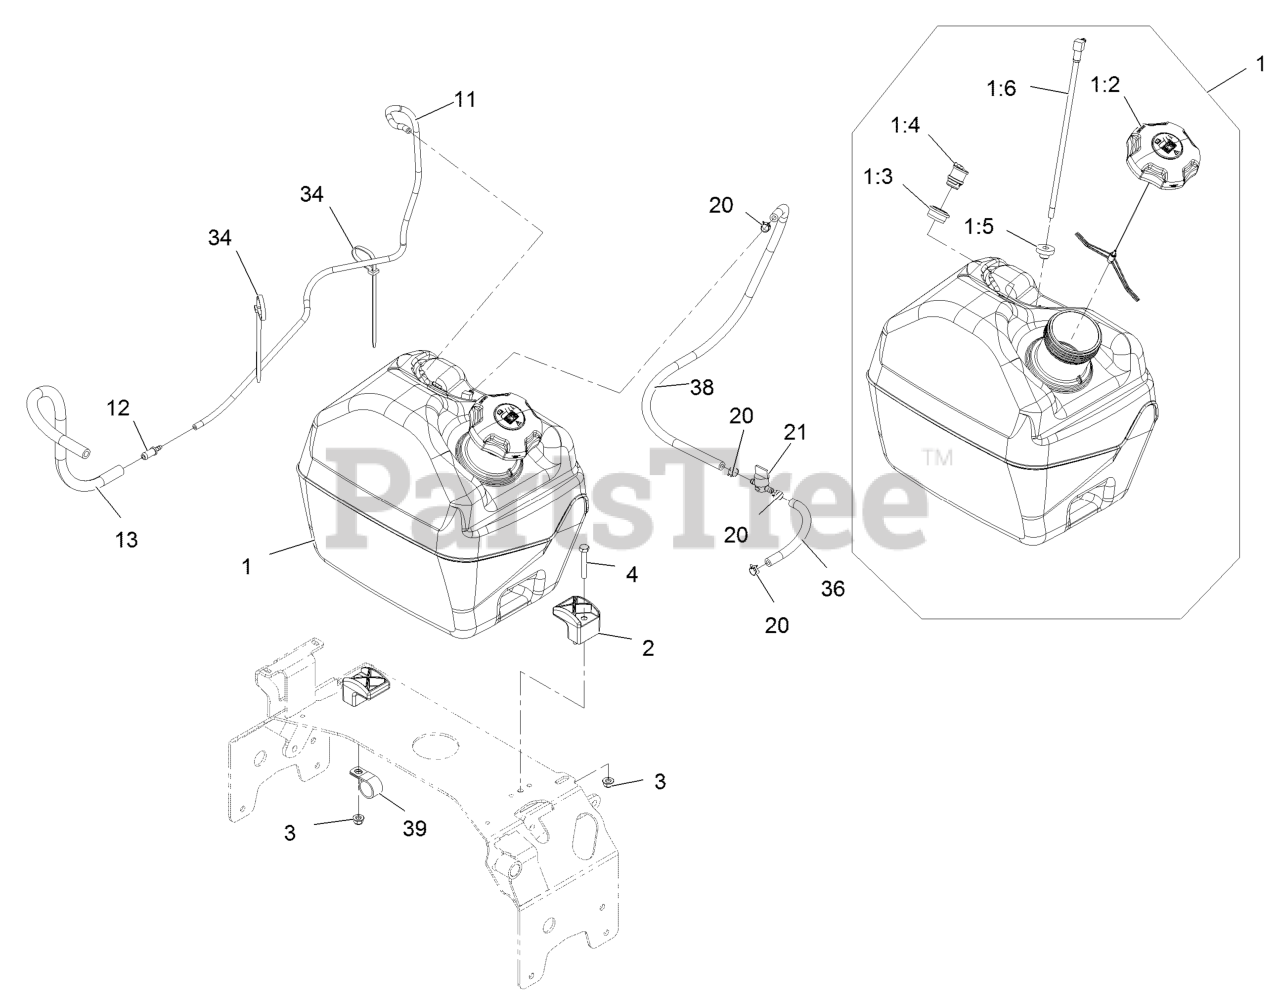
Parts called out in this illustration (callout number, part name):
1:2	CAP-FUEL, RATCHETING (3.5)
1:3	GROMMET
1:4	VALVE-VENT, FUEL
1:5	BUSHING
3	NUT-HF, NI
4	SCREW-HH
11	HOSE, EMISSIONS
12	FITTING-STRAIGHT
13	HOSE-FUEL
20	CLAMP-HOSE
21	VALVE-FUEL
34	TIE-PLASTIC
36	HOSE-FUEL
38	HOSE-FUEL
39	CLIP-LOOM
